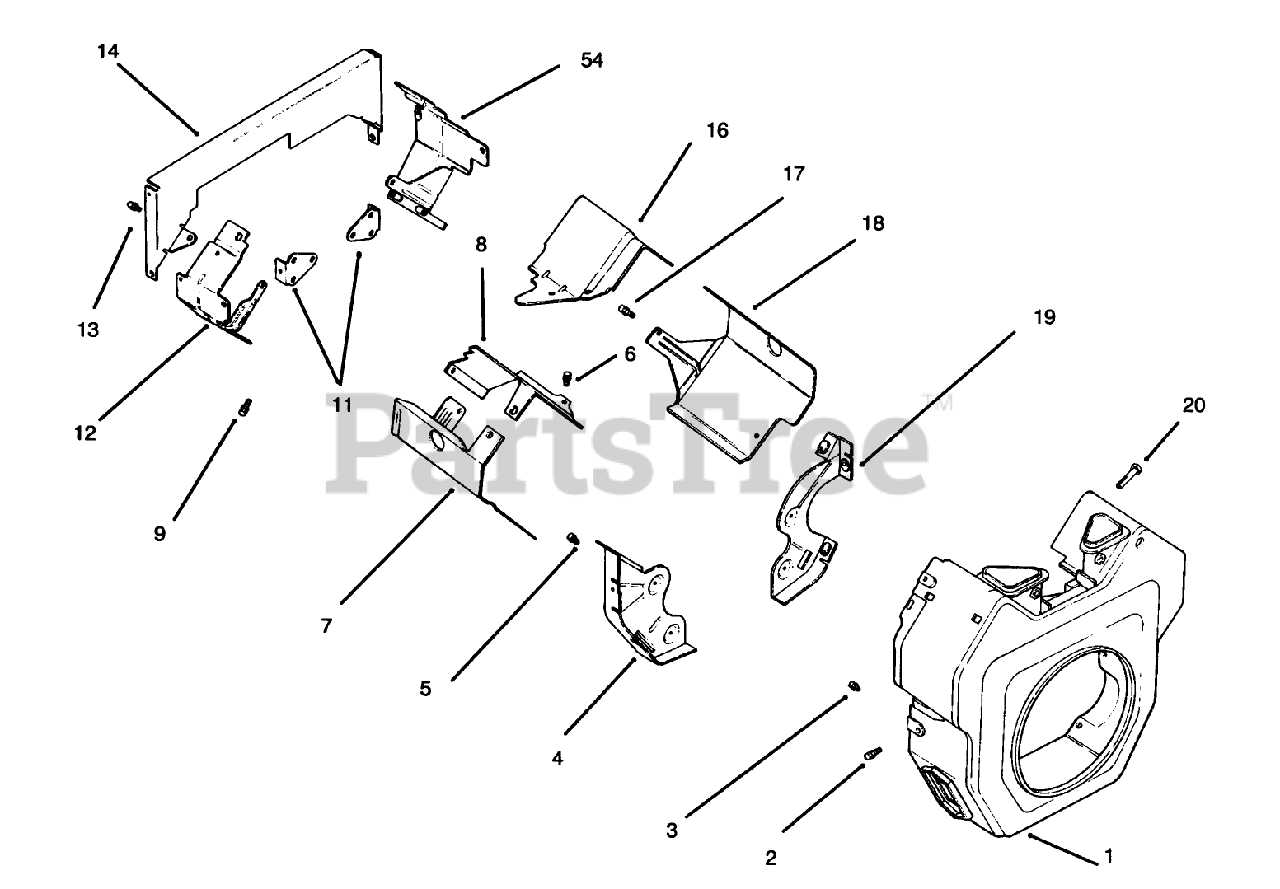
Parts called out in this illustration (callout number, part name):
1	Housing-Blower
4	Plate-Backing #2 side
7	Baffle Cylinder #2 Side
8	Baffle-Valley #2 side
11	Bracket-Support
12	Baffle-Ducted Air #1 side
14	Plat-Ducted Air Backing
15	Baffle-Ducted Air #1 side
16	Baffle, Valley 1 side
18	Baffle-Cylinder Barrel #1 side
19	Plate-Backing #1
